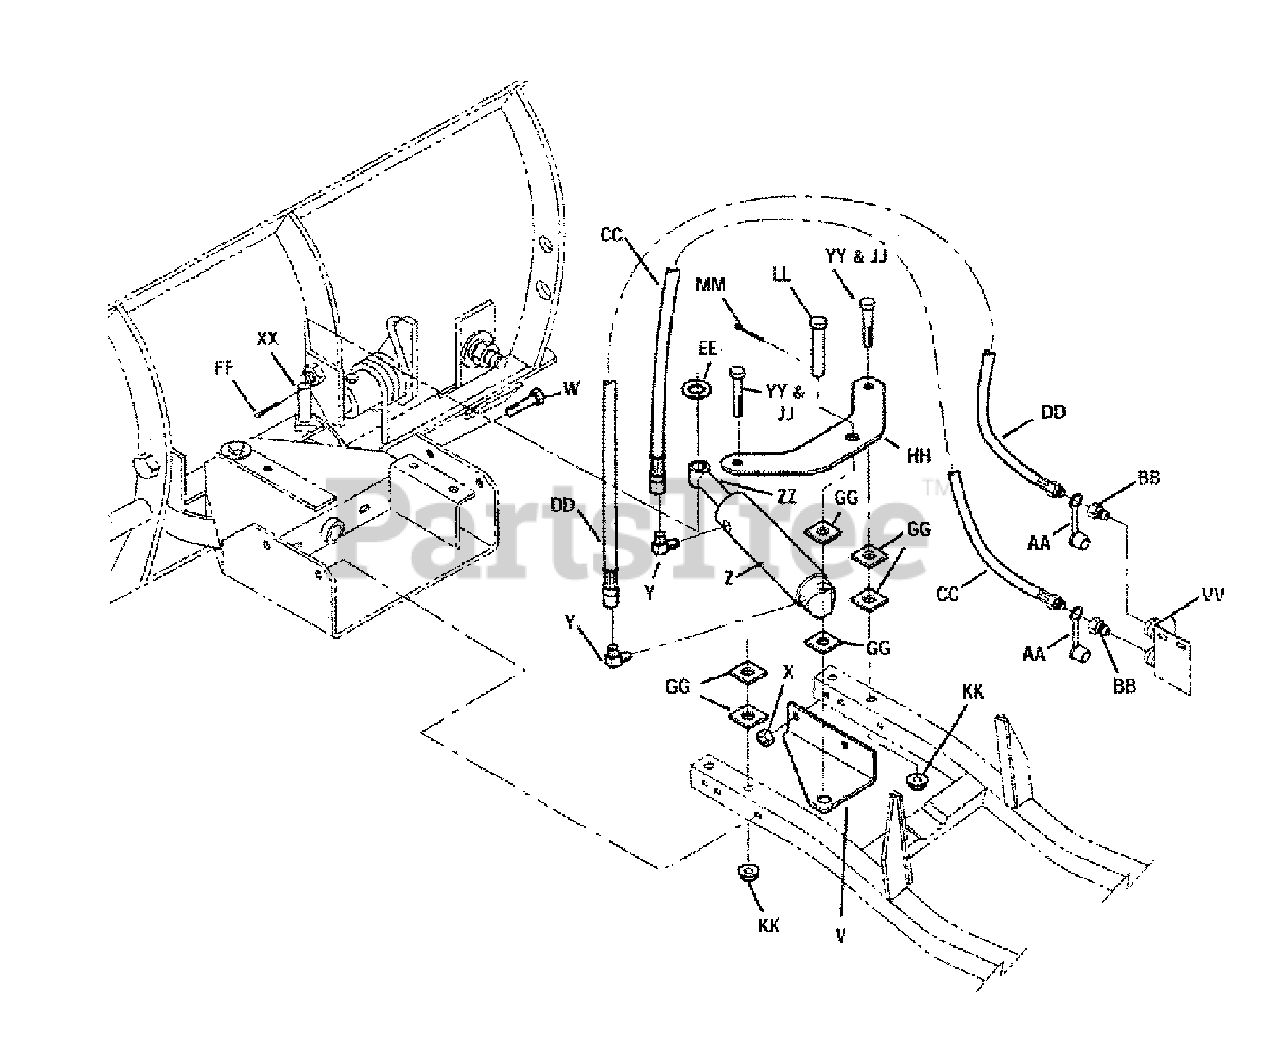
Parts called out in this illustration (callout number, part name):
V	Bottom Bracket - Cylinder Mounting
W	Hex hd. Screw, 5/16-18 x 2-1/2
X	Top Lock Nut, 3/8-16
Y	90° Elbow
Z	Hydraulic Cylinder Assembly
BB	Hydraulic Coupling
CC	Hydraulic Hose
DD	Hydraulic Hose
EE	Washer, 3/4
FF	Cotter Pin, 1/4 x 1-1/2
GG	Spacer Plate
HH	Top Bracket - Cylinder Mounting
JJ	Hex hd. Screw, 1/2-13 x 3
KK	Flange Lock Nut, 1/2-13
LL	Clevis Pin, 3/4
MM	Cotter Pin, 1-1/4 x 1-1/4
